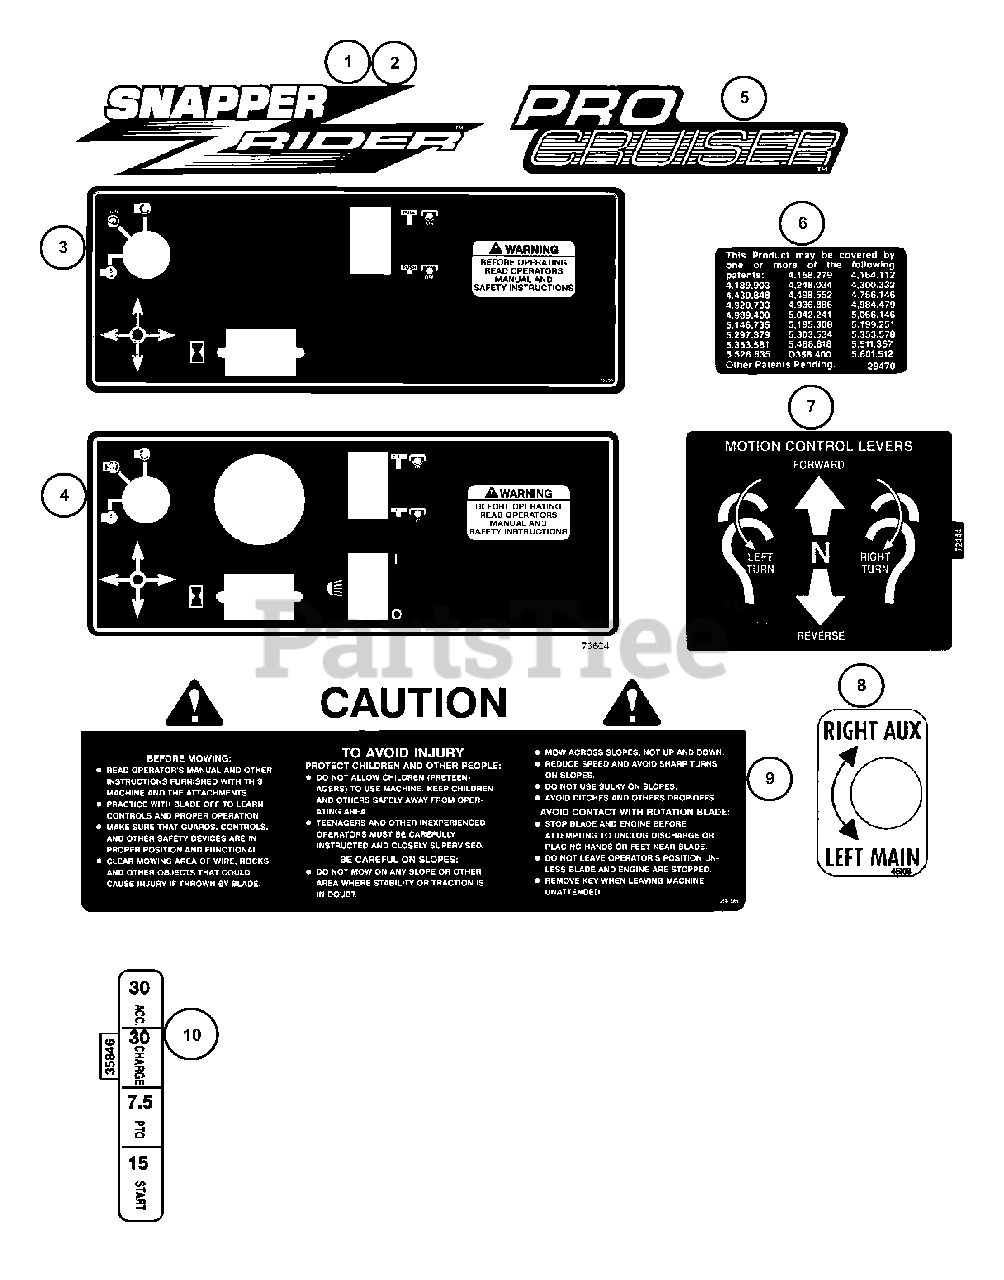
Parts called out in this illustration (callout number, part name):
1	LOGO, Side 24.5" Long
2	LOGO, Front 16.33" Long
3	DECAL, Control Panel (MZM Models)
4	DECAL, Control Panel
5	DECAL, Pro Cruiser
6	DECAL, Patent Numbers
7	DECAL, Twin Stick Control
8	DECAL, Tank Selector
9	DECAL, Caution
10	DECAL, Fuse
